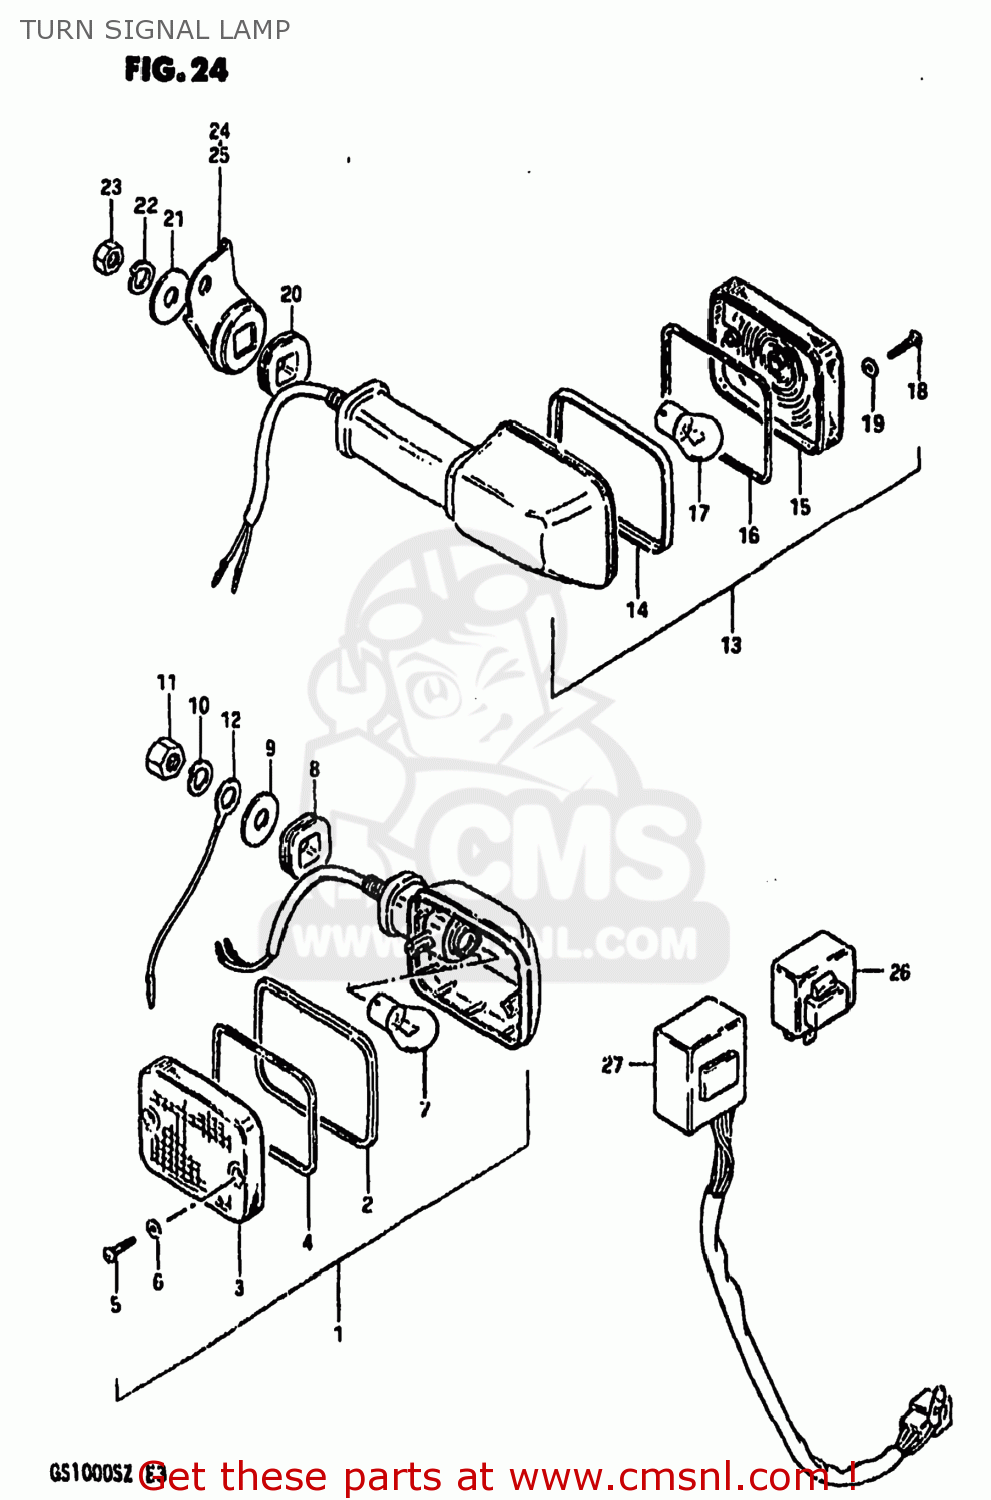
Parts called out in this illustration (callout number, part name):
1	SIGNAL LAMP
2	RIM
3	LENS
4	GASKET (NAS)
5	BULB(12V23W)
6	SCREW
7	GASKET (NAS)
8	CUSHION
9	WASHER (10.5X30X2.3)
10	LOCK WASHER
11	NUT
12	WIRE
13	LAMP ASSEMBLY,FRONT TURN SIGNAL
14	RIM
15	LENS
16	GASKET (NAS)
17	BULB(12V23W,STANLEY,A4577A)
18	SCREW
19	GASKET (NAS)
20	CUSHION
21	WASHER (10.5X30X2.3)
22	LOCK WASHER
23	NUT
24	BRACKET,RR TURNSIGNAL LAMP,R
25	BRACKET,RR TURNSIGNAL LAMP,L
26	RELAY ASSY,TURNSIGNAL
27	UNIT,TURN SIGNAL CONTROL
